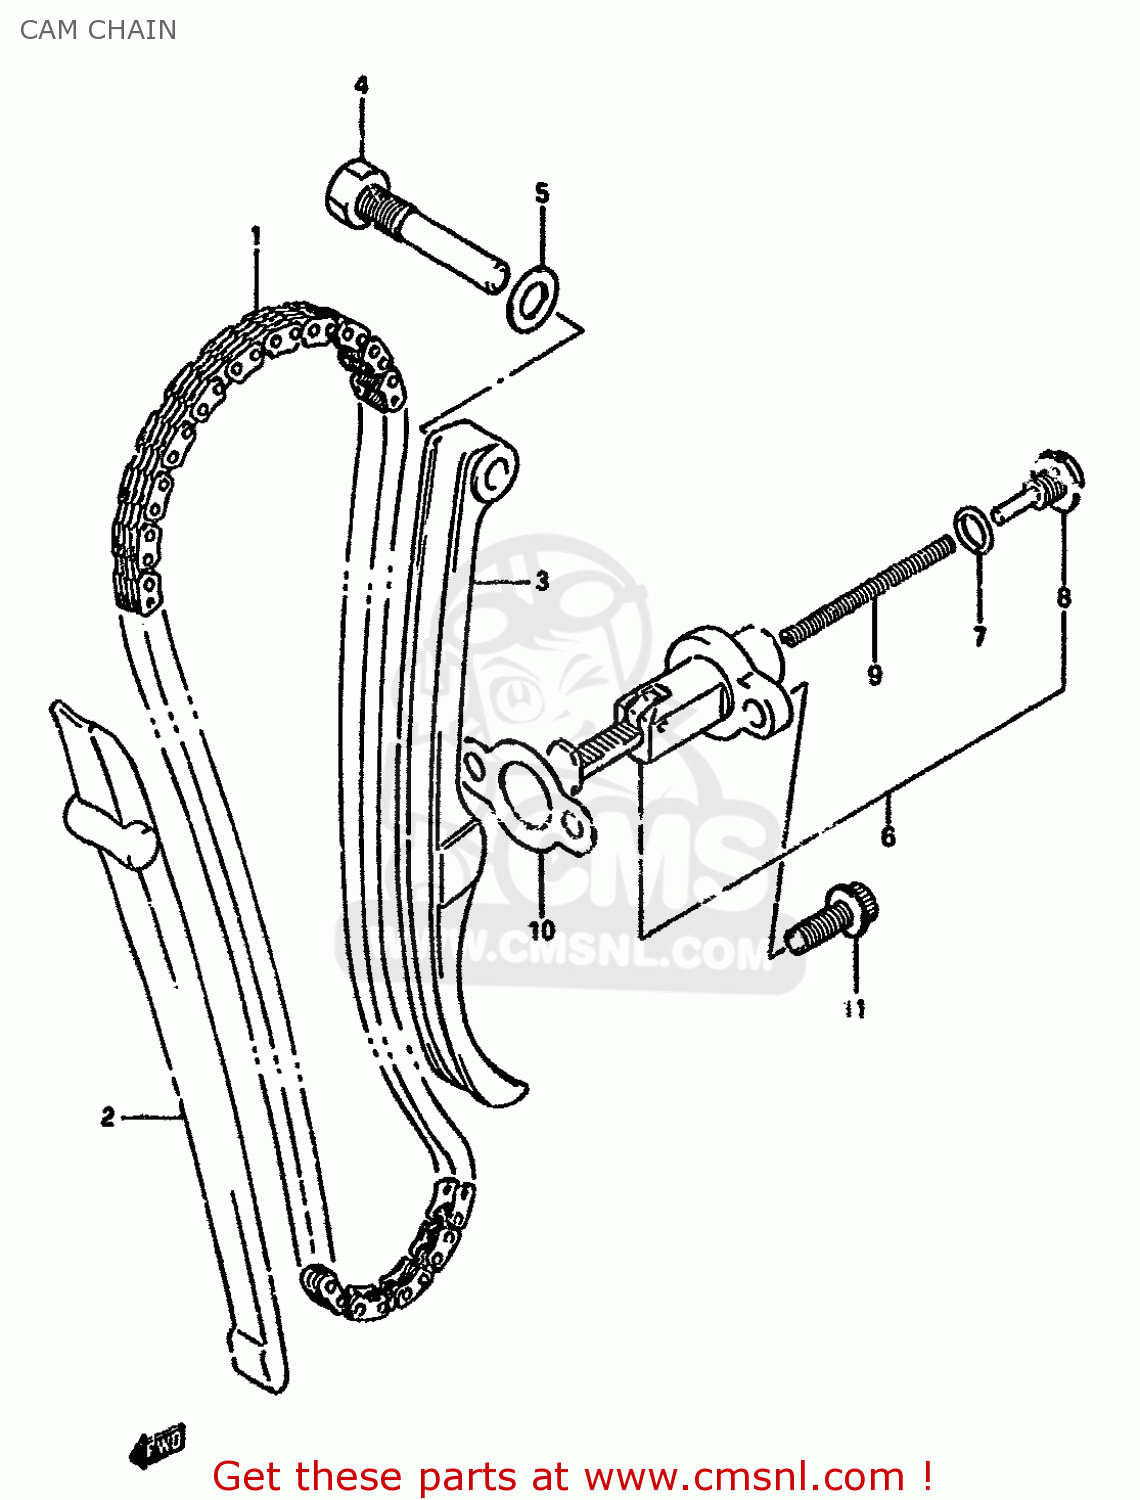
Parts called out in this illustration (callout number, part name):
1	CHAIN,CAMSHAFT DRIVE
2	GUIDE,CAM CHAIN
3	TENSIONER,CAM CHAIN
4	BOLT,CAM CHAIN TENSIONER
5	GASKET 8.2X14X1 (NAS)
6	ADJUSTER ASSY,TENSIONER
7	O RING
8	PLUG,ADJUSTER
9	SPRING
10	GASKET,TENSIONER ADJUSTER(NA) (NAS)
11	BOLT
